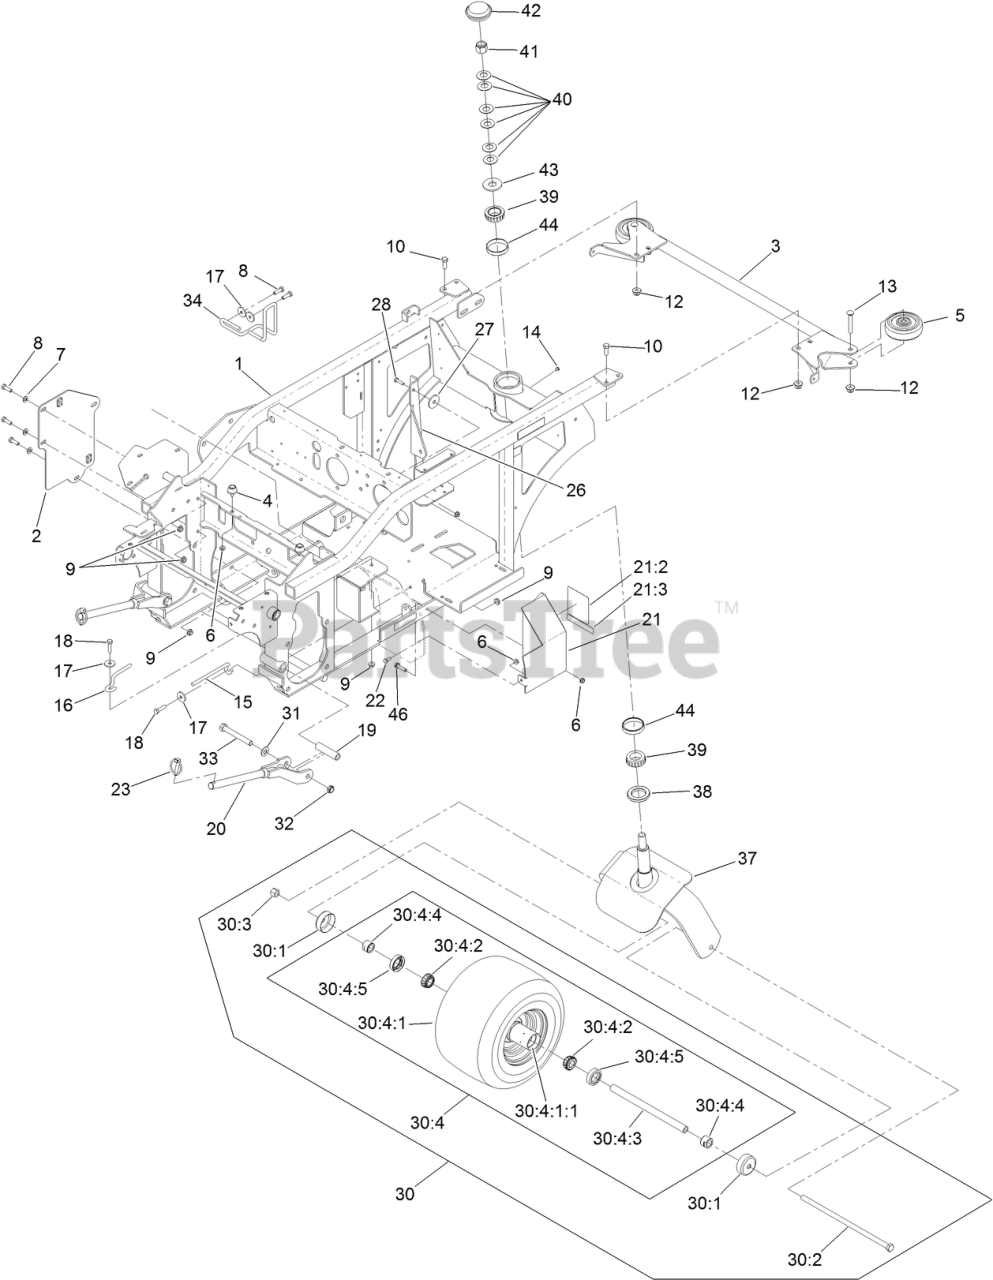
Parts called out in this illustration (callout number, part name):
1	FRAME ASM
2	PLATE-SUPPORT
3	BUMPER-REAR
4	BUMPER-RUBBER
5	ROLLER-BUMPER
6	NUT-HF
7	WASHER-PLAIN
8	SCREW-HH
9	NUT-HF
10	SCREW-HH
12	NUT-HF, NI
13	SCREW-CARR
15	GUIDE-BELT
16	GUIDE-BELT
17	WASHER
18	SCREW-HH
19	SPACER-WHEEL, SHORT
20	ROD-PUSH
21	SHIELD ASM-DRIVE
21:2	DECAL-BELT ROUTING
21:3	DECAL-WARNING
22	SCREW-HH
23	PIN-LYNCH
26	BRACE-PTO
27	WASHER
28	SCREW-HH
30	WHEEL AND AXLE ASM
30:1	GUARD-SEAL
30:2	SCREW-HH
30:3	NUT-LOCK, NI
30:4	WHEEL AND BEARING ASM
30:4:1	WHEEL AND TIRE ASM
30:4:1:1	BEARING-CUP
30:4:2	BEARING-CONE, TAPER
30:4:3	AXLE CASTER ASM
30:4:4	SPACER-NUT
30:4:5	SEAL-CASTER
31	WASHER-FLAT
32	NUT-HEX
33	SCREW-HH
34	WLD-BELT GUIDE
37	FORK-REAR CASTER
38	SEAL-GREASE
39	BEARING-ROLLER, CONE TAPER
40	WASHER-BELLVILLE
41	NUT-LOCK, NI
42	CAP-GREASE
43	WASHER-FLAT
44	CUP-TAPERED, ROLLER BEARING
46	SCREW-HHF
